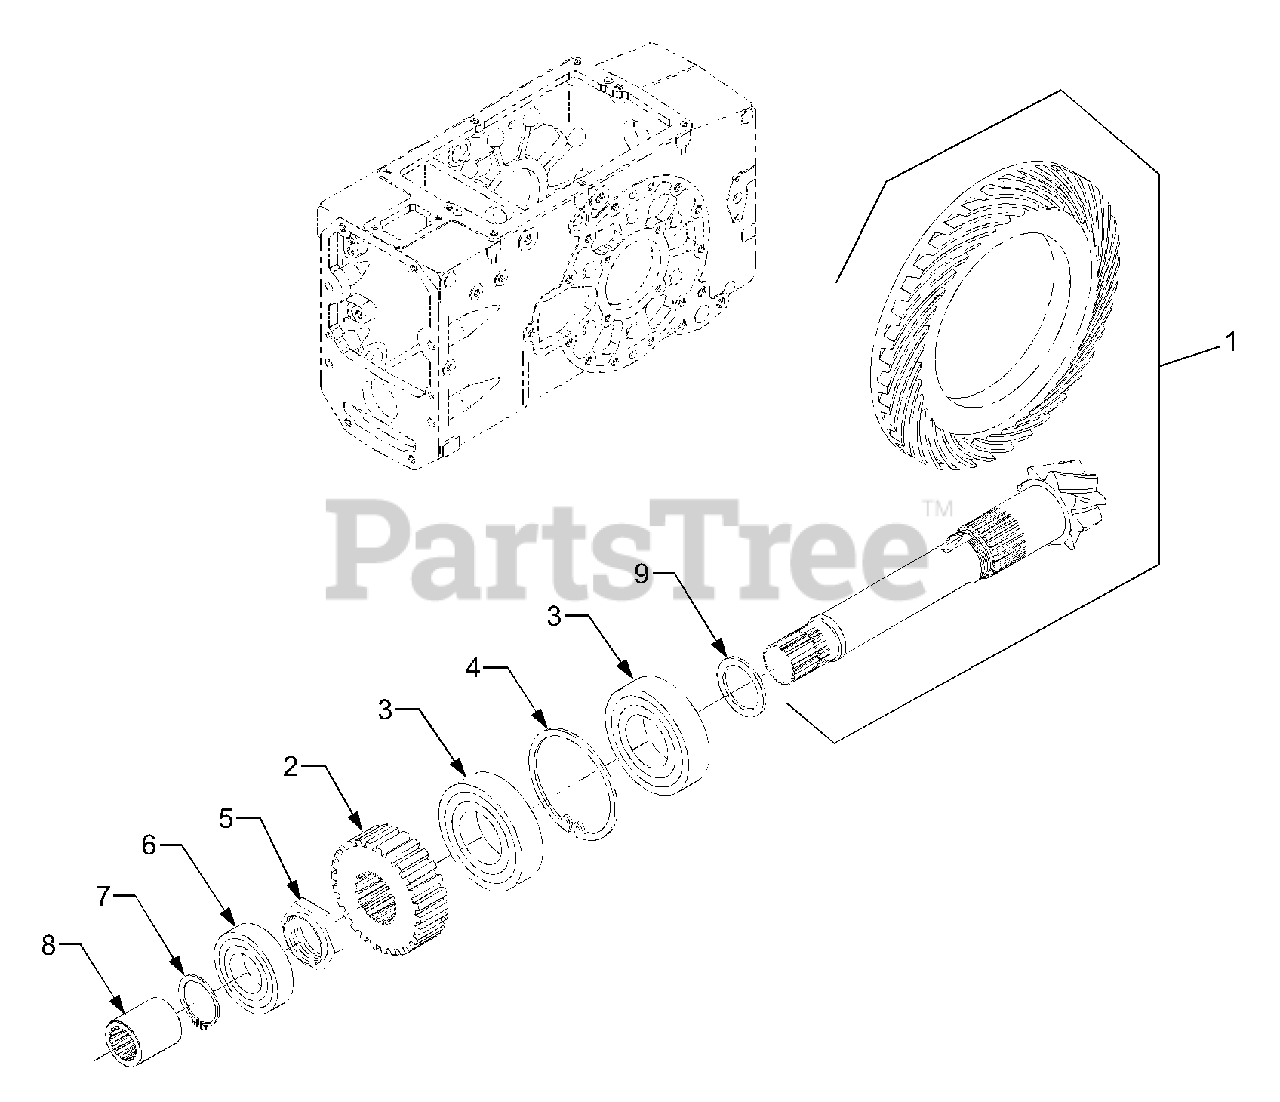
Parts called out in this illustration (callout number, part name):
1	Spiral Bevel Gear Ass'y
3	Bearing, Tapper Roller
6	Bearing, Ball
8	Coupling
9	Collar, Adjust (T 2.6)
